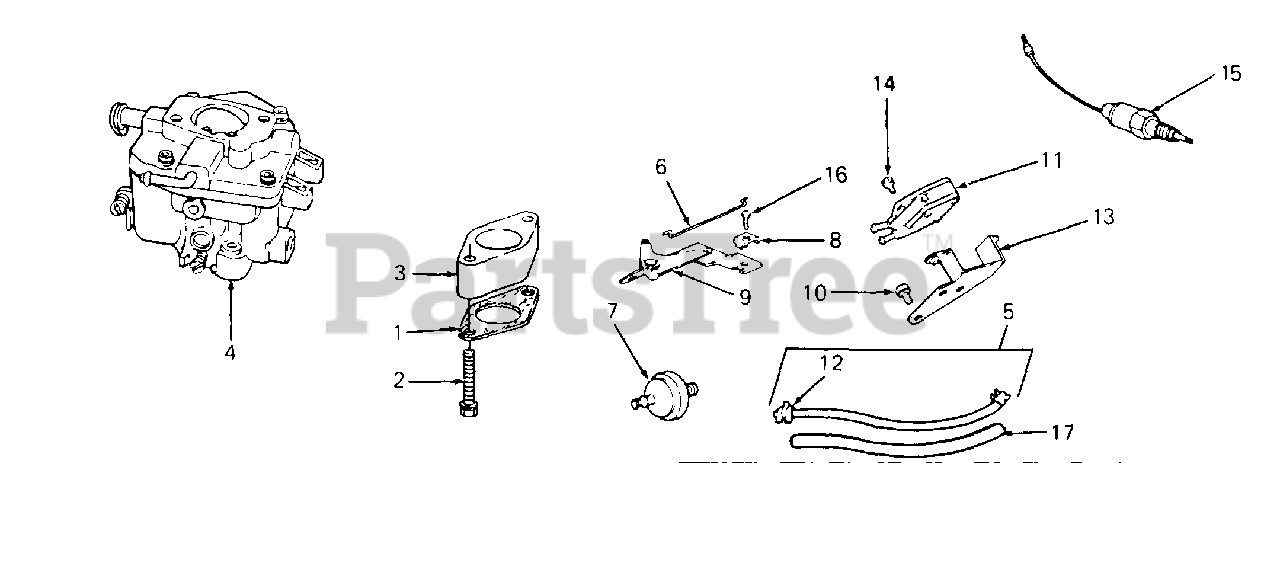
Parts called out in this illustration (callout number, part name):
1	Gasket, Carburetor Mtg
2	Screw, Sems
3	Spacer, Carburetor
4	Carburetor Assy
5	Line, Fuel
6	Link, Choke
7	Filter, Fuel
8	Clamp, Casing
9	Bracket, Choke
10	Screw, Sems
11	Pump, Fuel
12	Clamp, Fuel Line
13	Bracket, Fuel Pump
14	Screw, Mtg
15	Solenoid
16	Screw, Hex Hd
17	Insulation, Fuel Line
